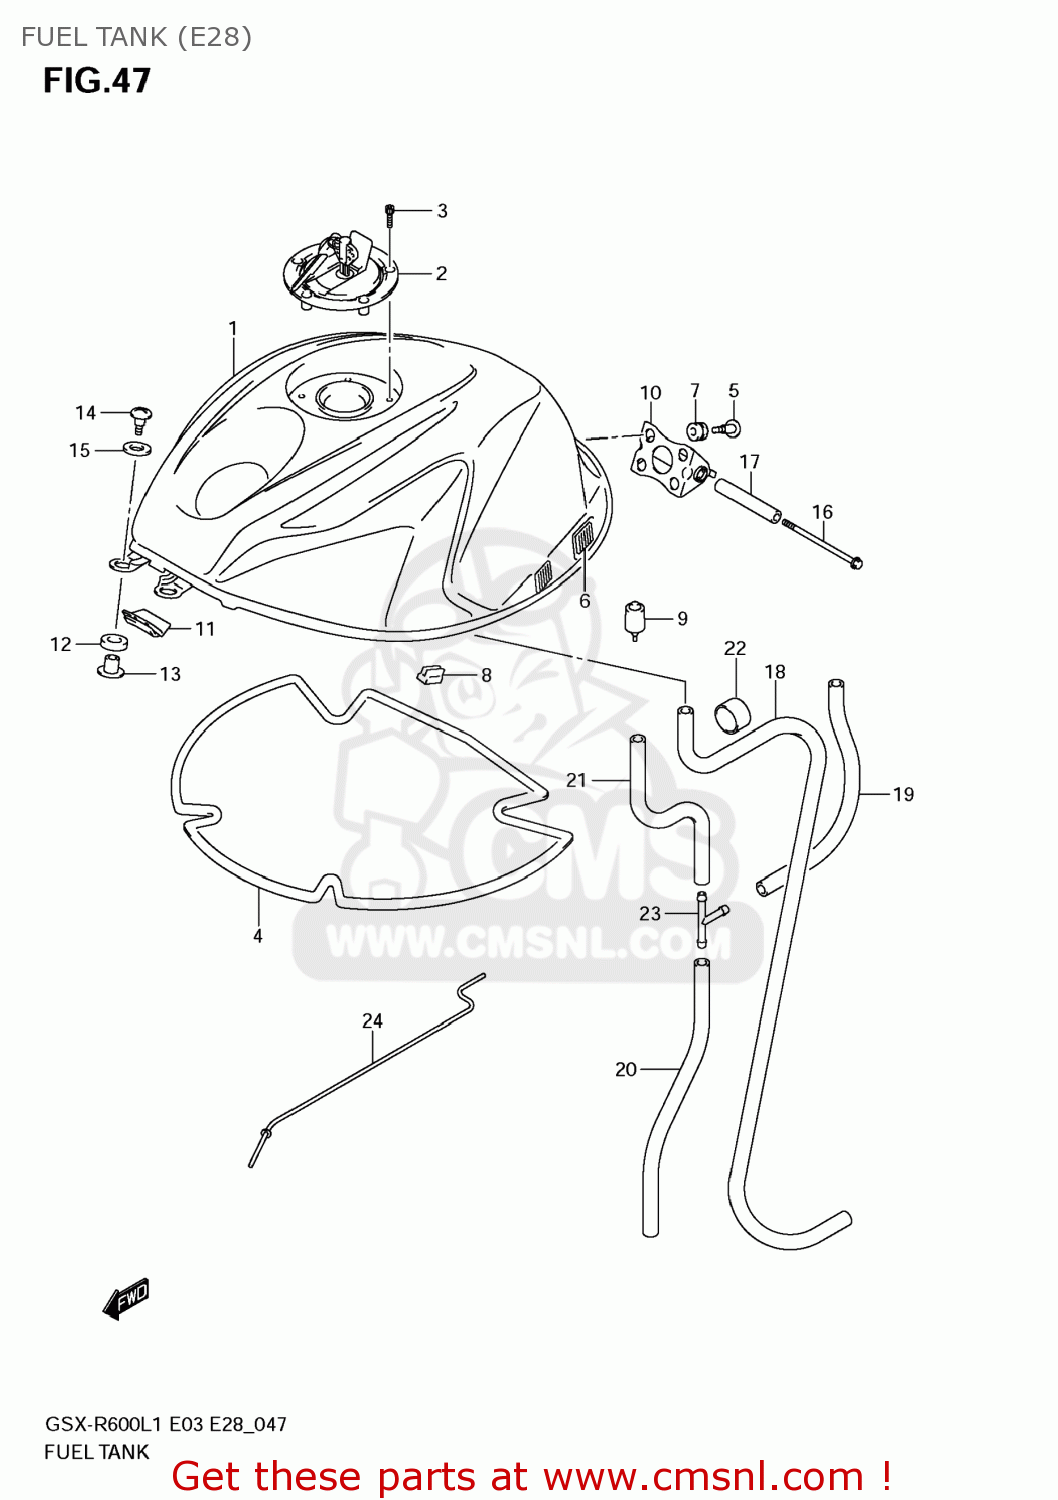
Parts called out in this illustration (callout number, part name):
1	TANK ASSY,FUEL
2	CAP SET,FUEL TANK
3	BOLT(5X20)
4	SHIELD,FUEL TANK HEAT
5	SCREW,FUEL TANK RR BRACKET
6	FASTENER
7	CUSHION
8	CUSHION,FUEL TANK COVER
9	CUSHION,FUEL TANK RR
10	BRACKET,FUEL TANK NO.1
11	RUBBER,FUEL TANK FR
12	CUSHION,FUEL TANK FR
13	SPACER,FUEL TANK FR
14	SCREW(6X25)
15	WASHER(6.5X22X1.6)
16	BOLT(6X110)
17	SPACER,FUEL TANK RR
18	HOSE,FUEL TANK WATER DRAIN
19	HOSE,FUEL TANK BREATHER NO.1
20	HOSE,FUEL TANK BREATHER NO.2
21	HOSE,VACUUM
22	HOSE(12X16X600)
23	3 WAY
24	STAY,FUEL TANK
